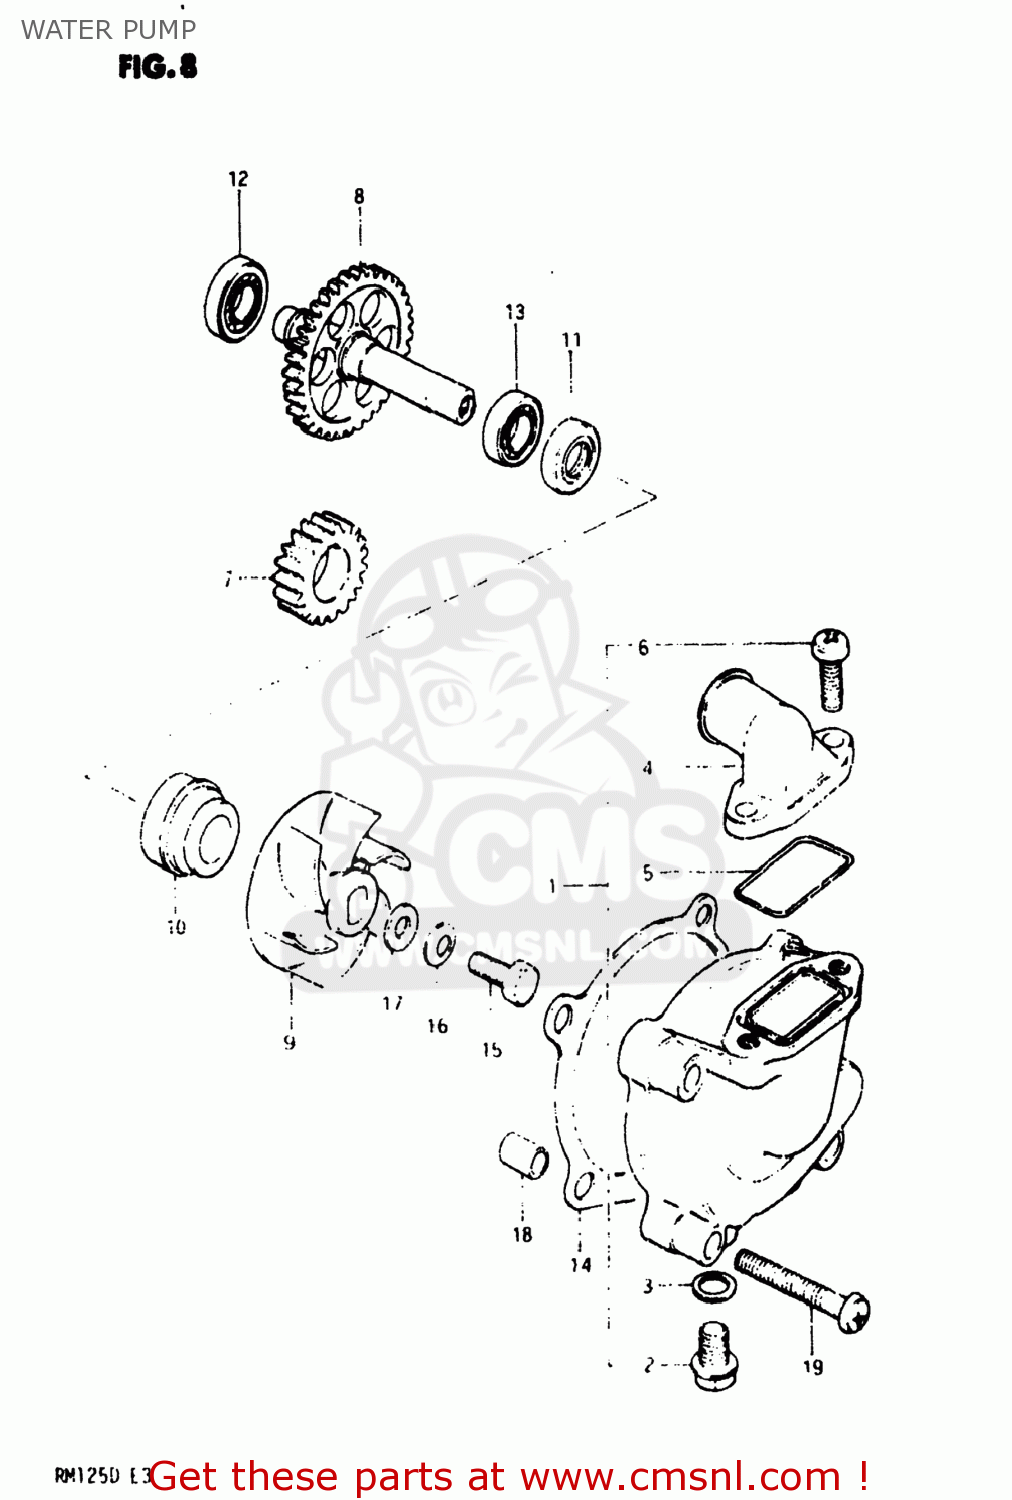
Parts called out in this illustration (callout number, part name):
1	CASE,WATER PUMP
2	BOLT,DRAIN
3	GASKET,DRAIN (NAS)
4	CONNECTOR
5	O RING,WATER PUMP CONNECTOR
6	SCREW
7	GEAR,WATER PUMP DRIVE
8	GEAR,WATER PUMP DRIVEN(NT:36)
9	IMPELLER,WATER PUMP
10	SEAL,WATER PUMP SHAFT
11	SEAL,OIL(10X21X5)
12	BEARING(10X22X6)
13	BEARING
14	GASKET,WATER PUMP CASE (MCA)
15	BOLT(6X13)
16	WASHER
17	GASKET (NAS)
18	PIN
19	SCREW
